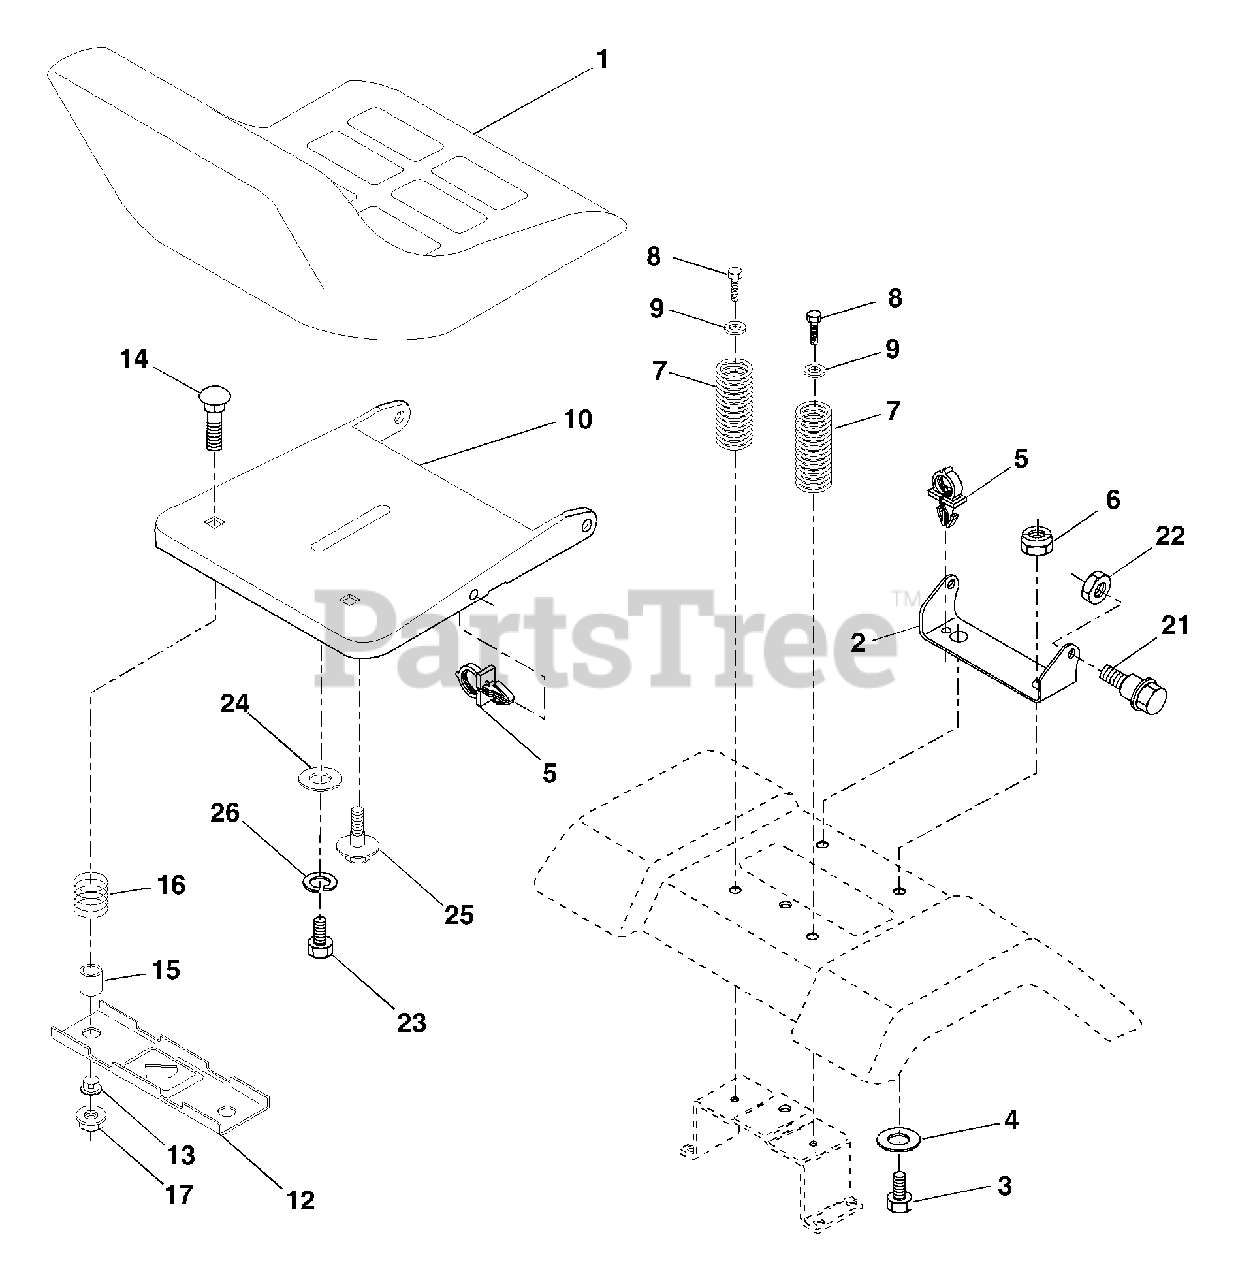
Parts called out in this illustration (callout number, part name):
1	Seat
2	Bracket Pnt Pivot Seat (blk )
3	Bolt
4	Washer 13/32 x 1 x 10 Ga
5	Clip Push-In Hinged
6	Nut
7	Spring Seat Cprsn 2 250 Blk Zi
8	Screw 3/8-16 x 1.5
9	Washer 13/32 x 1 x 14 Ga
10	Pan Pnt Seat (blk )
12	Bracket Pnt Mounting Switch
13	Bushing Snap Blk Nyl 50 Id
14	Bolt Rdhd Sht Nk 1/4-20 x 1-1/2
15	Spacer Split 28 x 96 Yel Zinc
16	Spring Cprsn 1 27 Blk Pnt
17	Nut Lock 1/4 Lge Flg Gr 5 Zinc
21	Bolt Shoulder 5/16-18 Unc Blkz-2A
22	Nut
23	Bolt Hex Black
24	Washer 17/32 x 1-3/16 x 12 Ga
25	Bolt Shoulder 5/16-18 x 62
26	Lockwasher
